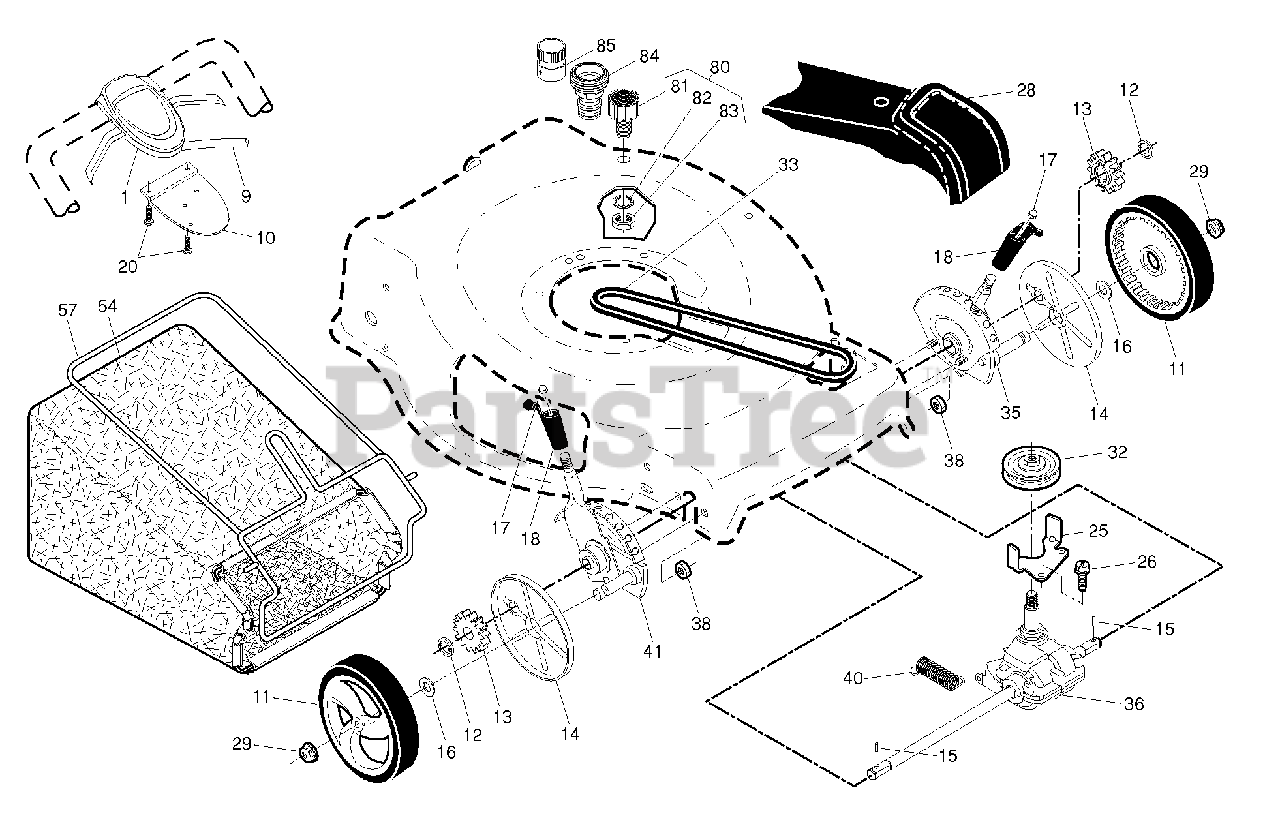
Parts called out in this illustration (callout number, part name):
10	BRACKET.DRIVE.CONTR.GEN2.BLACK
12	E-RING 7/16 RE
13	PINION.14.TEETH.FGD
14	COVER.DUST.WHEEL
15	PAWL, DRIVE
16	WASHER FLUT
20	SCREW, PHILLIPS HEAD 10 X 5/8
25	BRACKET.BELT.GUIDE.22+FGD.BZP
29	NUT.HEX.FLANGE.3/8-16.LOCKNUT
32	PULLEY.DRIVE.EZ/VARI.SCREWON
33	BELT.DRIVE.FGD.
38	NUT.HEX.FLANGE.1/4
57	FRAME.GBAG.22PLUS
80	KIT.WASH-OUT.PORT
81	FITTING, HOSE, WATER WASHOUT
82	WASHER.LOCK.INTERNAL.TOOTH
83	LOCKNUT.HEX.WITH.O-RING
85	COUPLING.QUICK CONNECT
